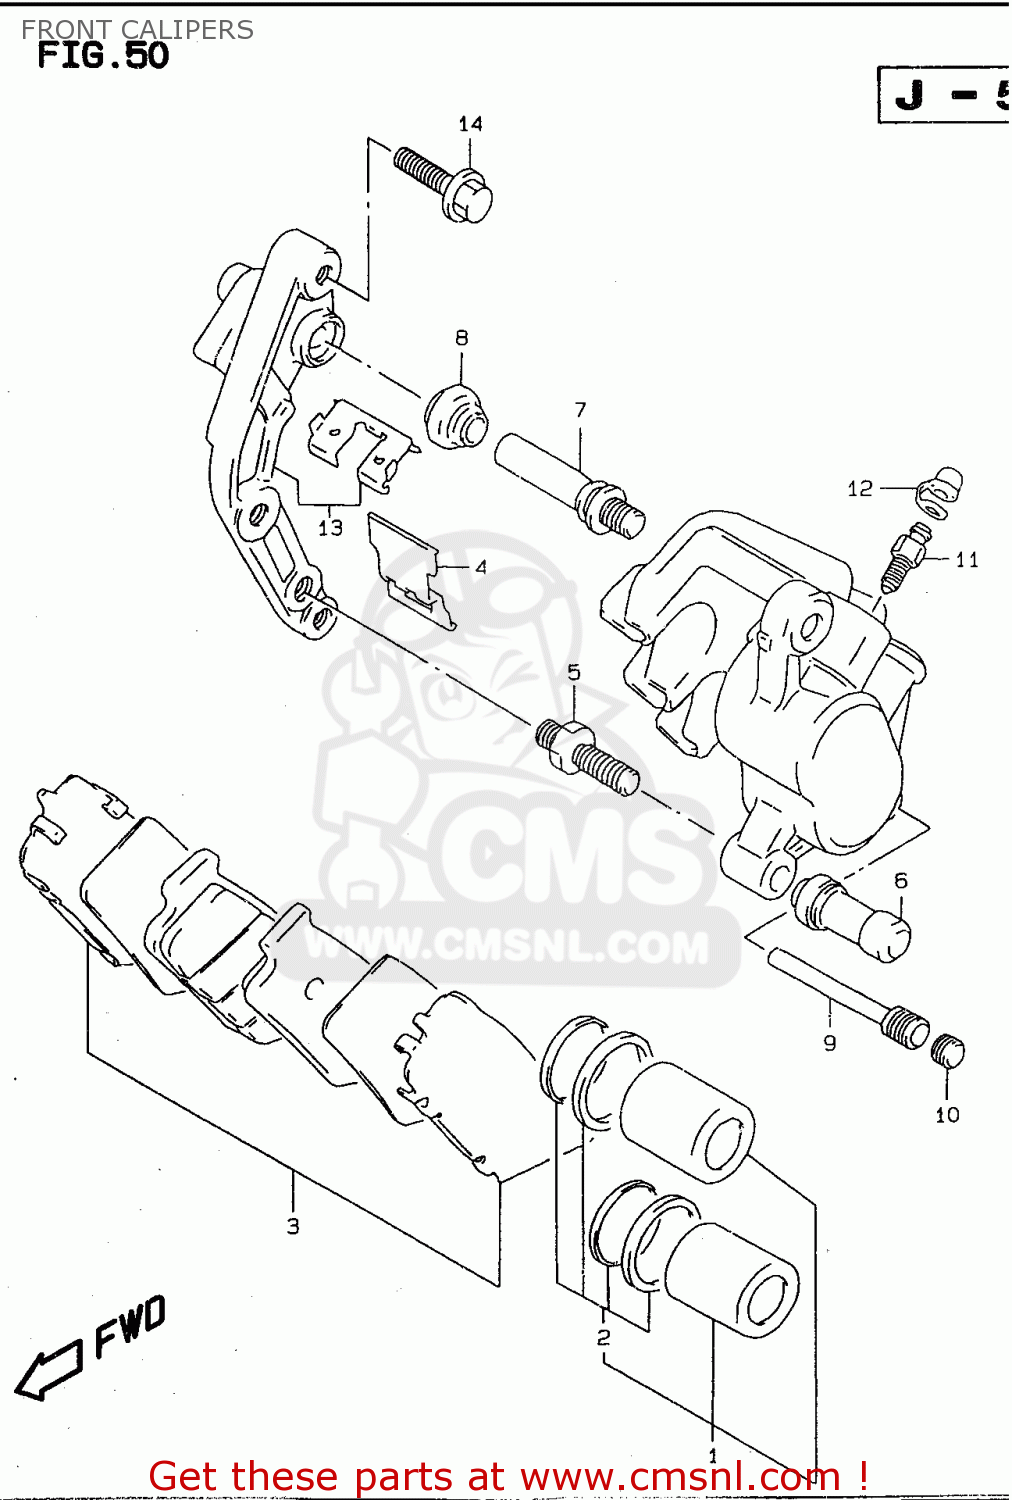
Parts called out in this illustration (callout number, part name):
1	PISTON SET
2	SEAL SET,PISTON
3	PAD & RETAINER SET
4	SPRING,PAD
5	PIN,BOLT
6	BOOT
7	PIN
8	BOOT
9	PIN,HANGER
10	PLUG,PIN
11	BLEEDER
12	CAP,BLEEDER
13	BRACKET,R
14	BOLT(8X30)
